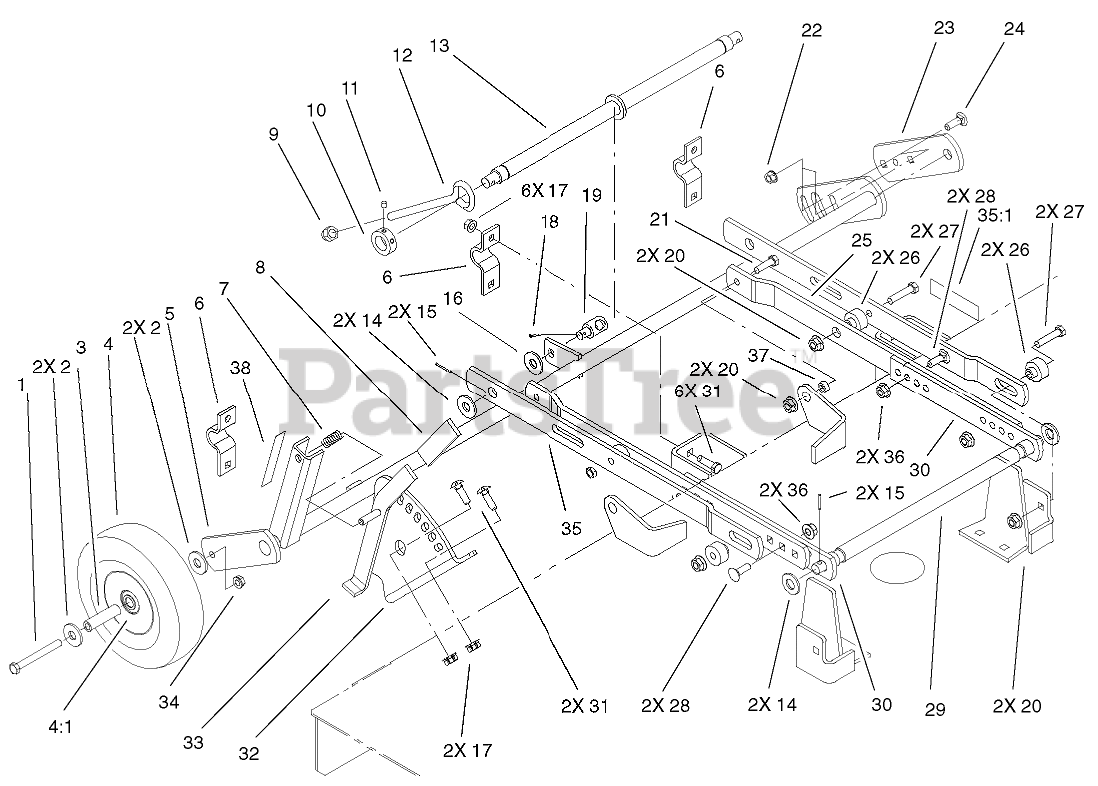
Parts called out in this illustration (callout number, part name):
1	SCREW-HH
2	WASHER-FLAT
3	SPACER
4	ASSY-GAUGE WHEEL
4:1	Bearing-Ball
5	WHEEL SUPPORT
6	Clamp
7	SPRING-COMPRESSION
9	NUT-LOCK, NI
10	COLLAR
11	SCREW-SET, HSH
12	ROD-ADJUSTMENT, LEVEL
13	SHAFT-LEVELER
14	WASHER-FLAT
15	PIN-ROLL, SPIROL
16	WASHER-FLAT
17	NUT-LOCK, NI
18	PIN-COTTER
19	TRUNNION
20	LOCKNUT-FLANGE
21	SCREW-HH
22	NUT-FLANGE
23	SUPPORT-GAGE WHEEL
24	BOLT-CARR
25	DRAFTBAR
26	SPACER
27	SCREW-HH
28	SCREW-CARR
29	SHAFT-DRAFTBAR
30	DRAFTBAR-ADJUSTMENT
31	BOLT-CARR
32	QUADRANT-DECK
33	HOC Lever
34	NUT-HEX
35	LH Leveler ASM (only on: 78469)
35	RH Leveler ASM (only on: 78395)
35	RH Leveler ASM (only on: 78469)
35	LH Leveler ASM (only on: 78395)
35:1	Decal-Warning (only on: 78469)
35:1	Decal-Warning (only on: 78395)
36	NUT-LOCK, CONE
37	SPACER
38	Decal-HOC (only on: 78395)
